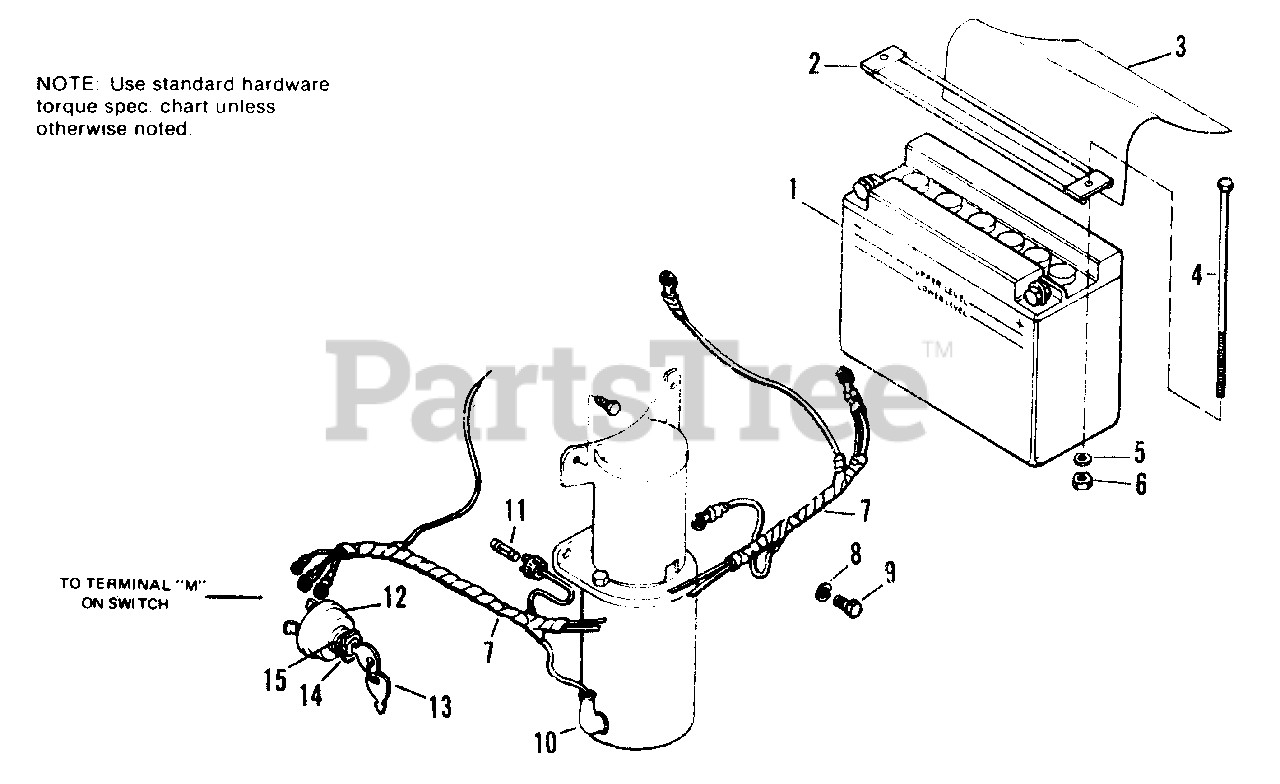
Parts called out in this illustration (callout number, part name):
2	HOLD DOWN, Battery
3	INSULATION, Battery
4	CAPSCREW, Hex Hd., 1/4-20 x 7
5	LOCKWASHER, 1/4
6	NUT, Hex, Full, 1/4-20
7	HARNESS ASSY.
8	LOCKWASHER, 5/16
9	CAPSCREW, Hex Hd., 5/16-18 x 5/8
10	COVER, Terminal
12	SWITCH, W/Keys
14	NUT, Hex, Special
15	LOCKWASHER, Int., 5/8
